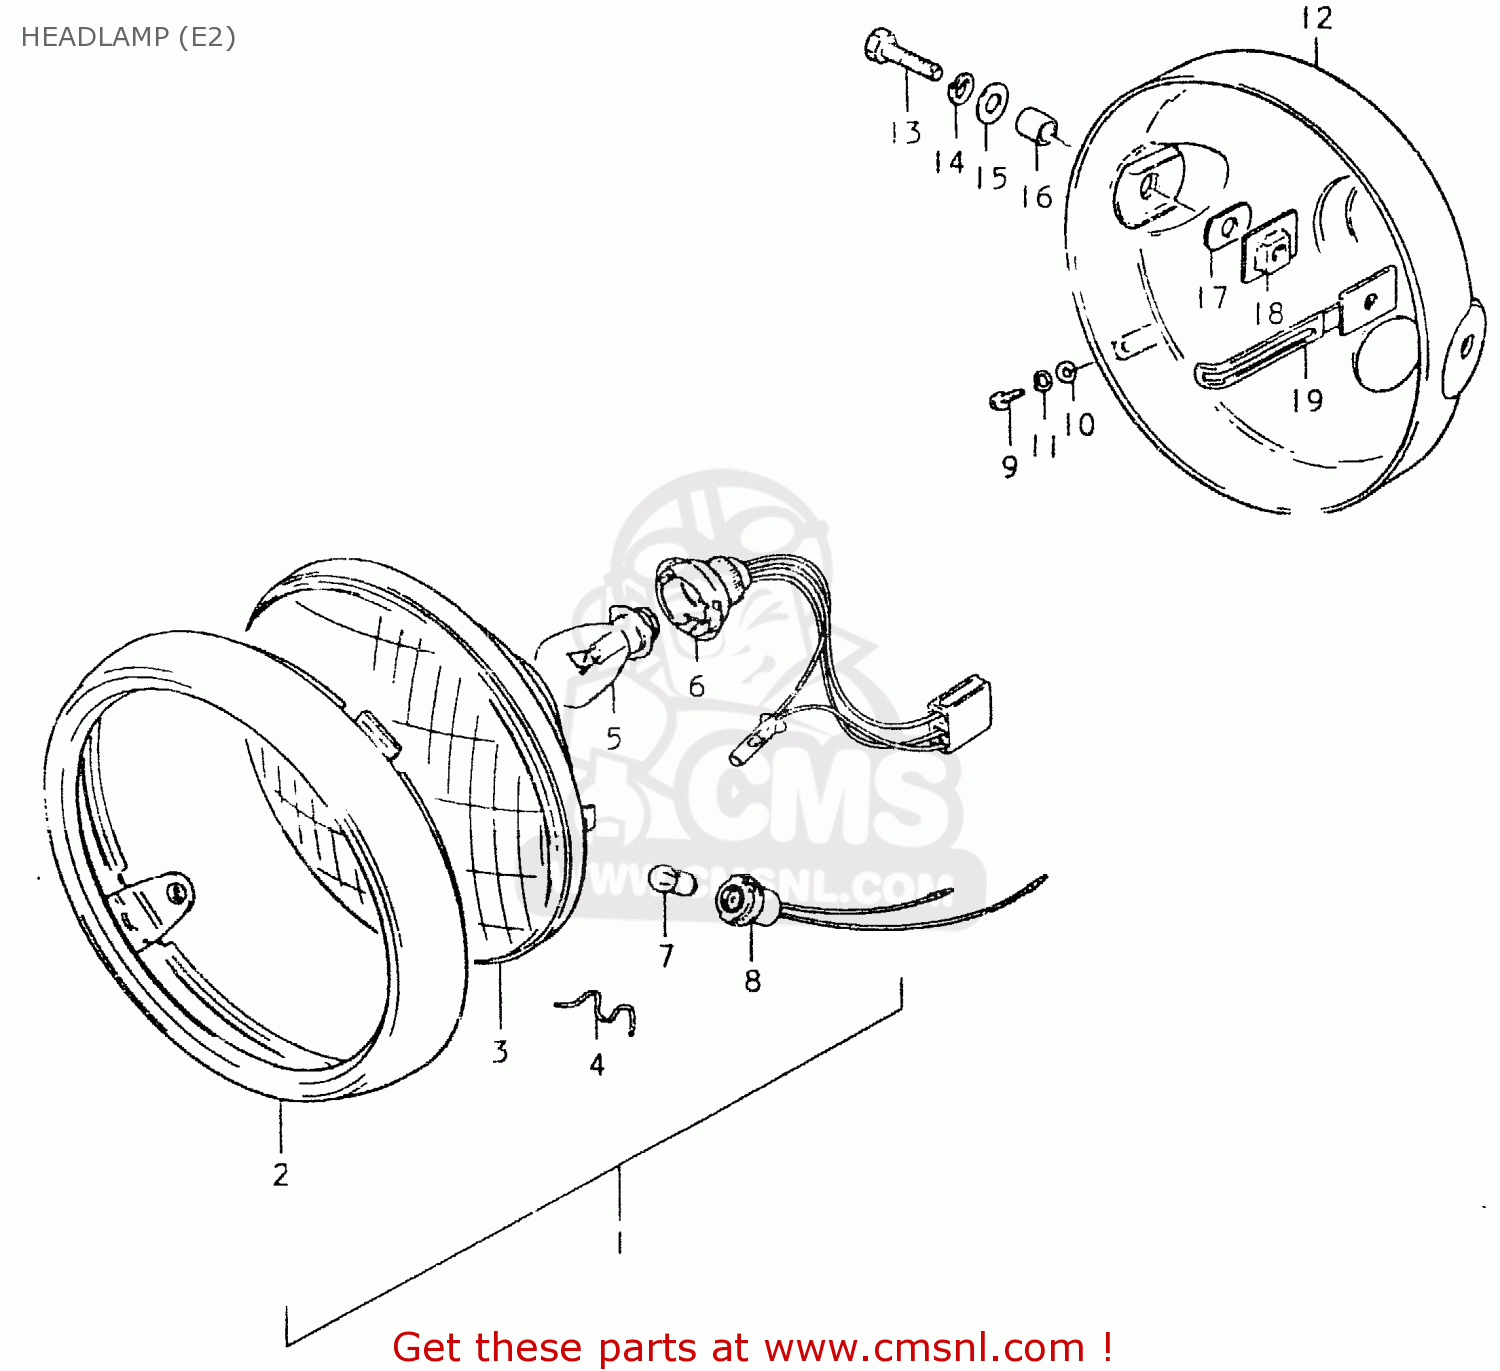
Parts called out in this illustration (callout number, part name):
1	HEADLAMP ASSY
2	RIM
3	UNIT
4	SPRING
5	BULB(6V,35/35W)
6	SOCKET
7	BULB(6V/3W)
8	SOCKET
9	SCREW
10	WASHER
11	LOCK WASHER
12	HOUSING,HEADLAMP
13	BOLT
14	LOCK WASHER
15	WASHER
16	SPACER (8.8X12X7)
17	CUSHION
18	PLATE,HEADLAMP HOUSING
19	PLATE,HEADLAMP HOUSING
